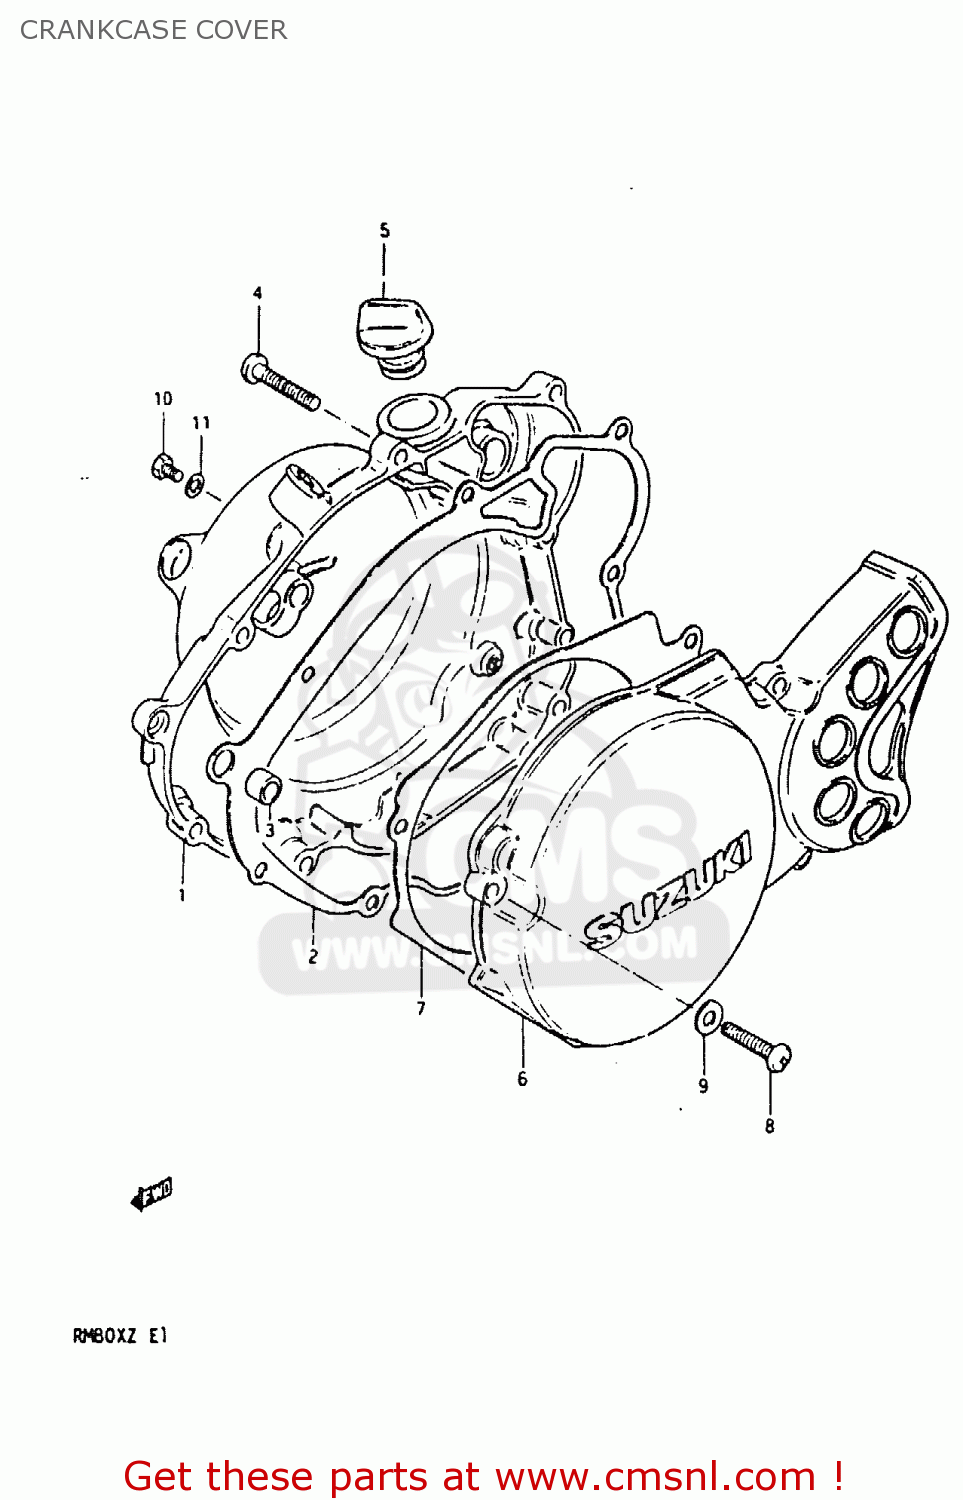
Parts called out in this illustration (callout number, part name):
1	COVER,CLUTCH
2	GASKET,CLUTCH COVER (MCA)
3	PIN
4	SCREW
5	PLUG
6	COVER
7	GASKET,MAGNETO COVER (NAS)
8	SCREW 5X20
9	WASHER
10	SCREW(6X10)
11	GASKET(6.2X11X1) (NAS)
